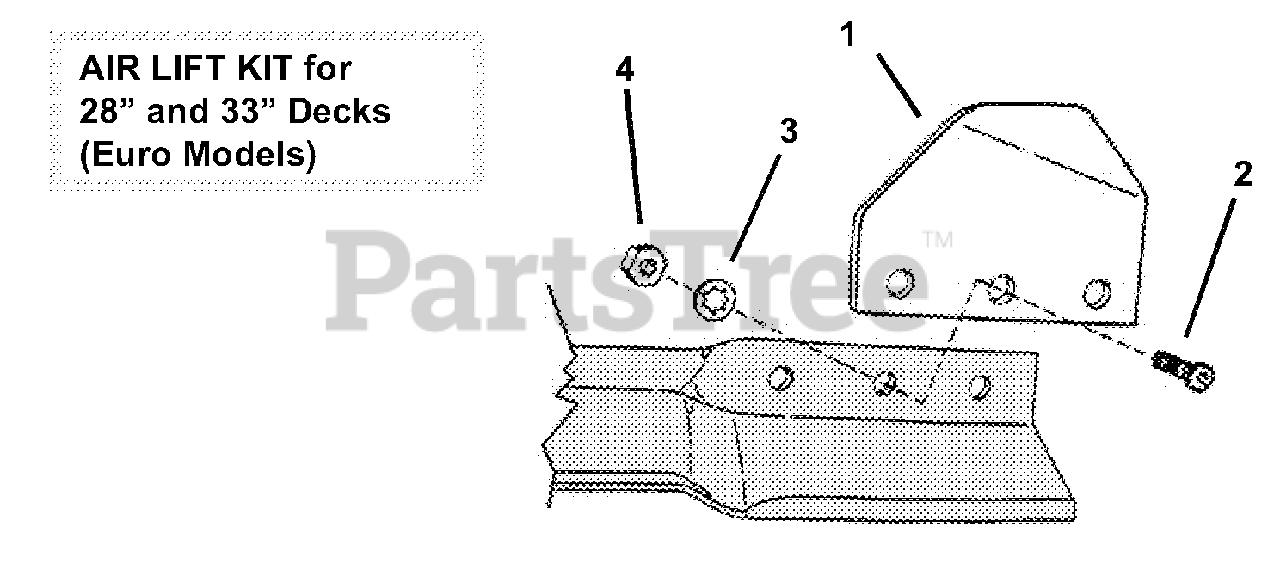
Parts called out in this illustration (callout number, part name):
1	AIR LIFT
2	SCREW, 5/16-24 Machine
3	WASHER, 5/16" Internal Tooth Lock
4	NUT, 5/16-24 Hex
